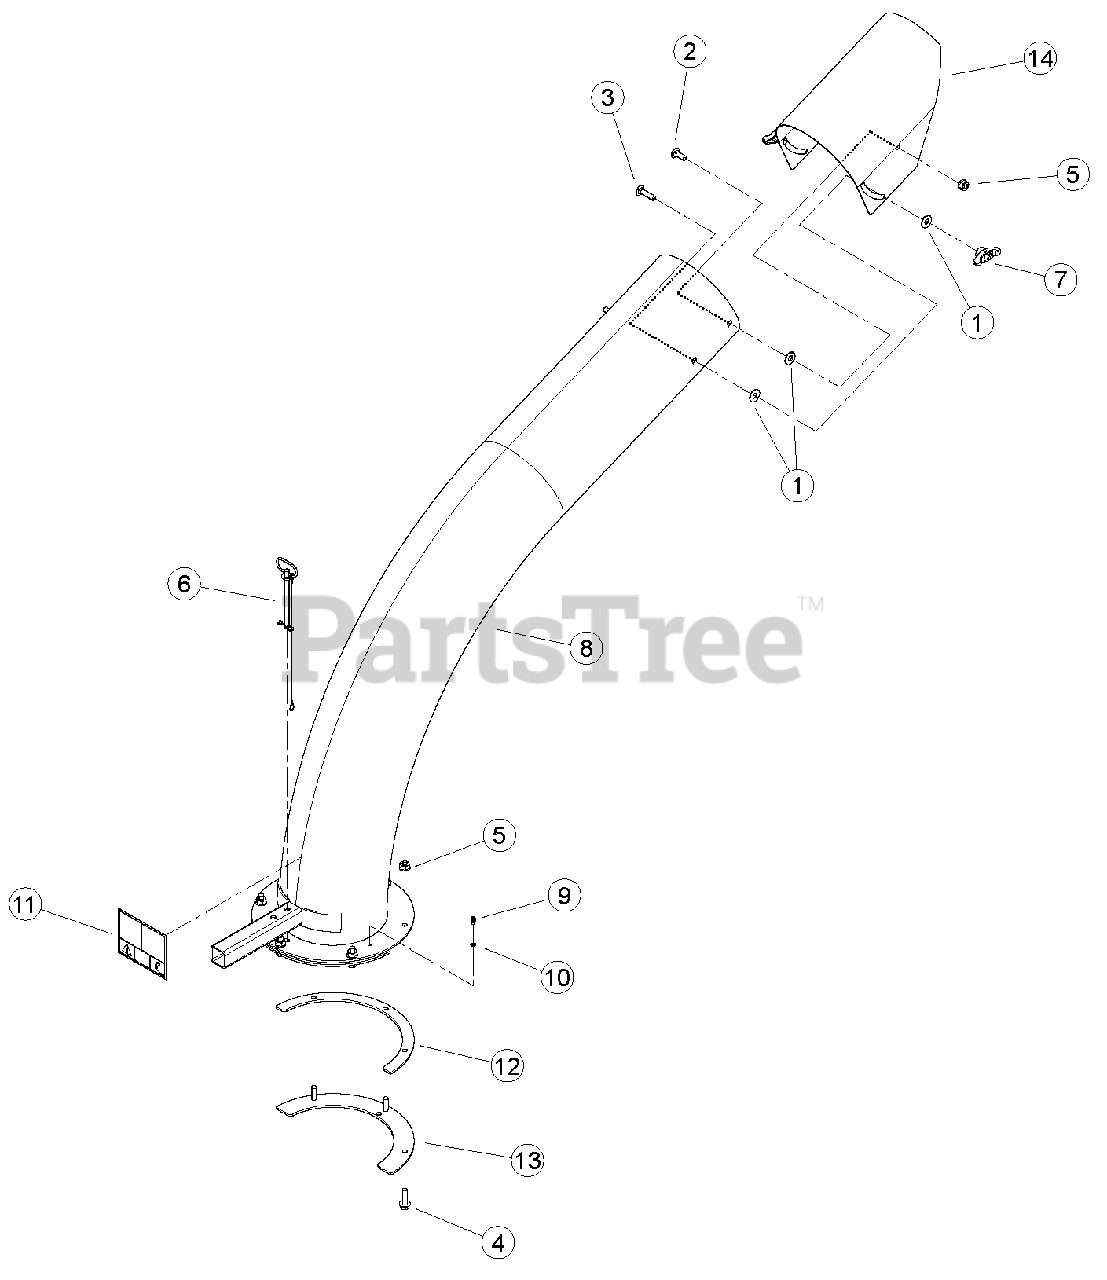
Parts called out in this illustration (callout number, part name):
1	WASHER, 3/8" FLAT ZP
2	BOLT, 3/8 X 1" GR5 CRG NC ZP
3	BOLT, 3/8 X 1-1/2" GR5 CRG NC ZP
4	BOLT, 3/8 X 1-1/4 FLANGE NC
5	NUT, 3/8-16 NYLOCK FLANGE
6	PIN, 3/8 X 4.25" DISCHARGE
7	KNOB, 3/8-16 UNC FEMALE TEE
8	ASSEMBLY, 8 INCH DISCHARGE CHUTE
9	FITTING, 1/4 SELF-TAP GREASE
10	WASHER, FLAT .254 X .400 X .048
11	DECAL, DISCHARGE DEBRIS & LOCK
12	RING, DISCHARGE SPACER
13	RING, DISCHARGE CLAMP
14	CAP, 8 INCH DISCHARGE CHUTE
